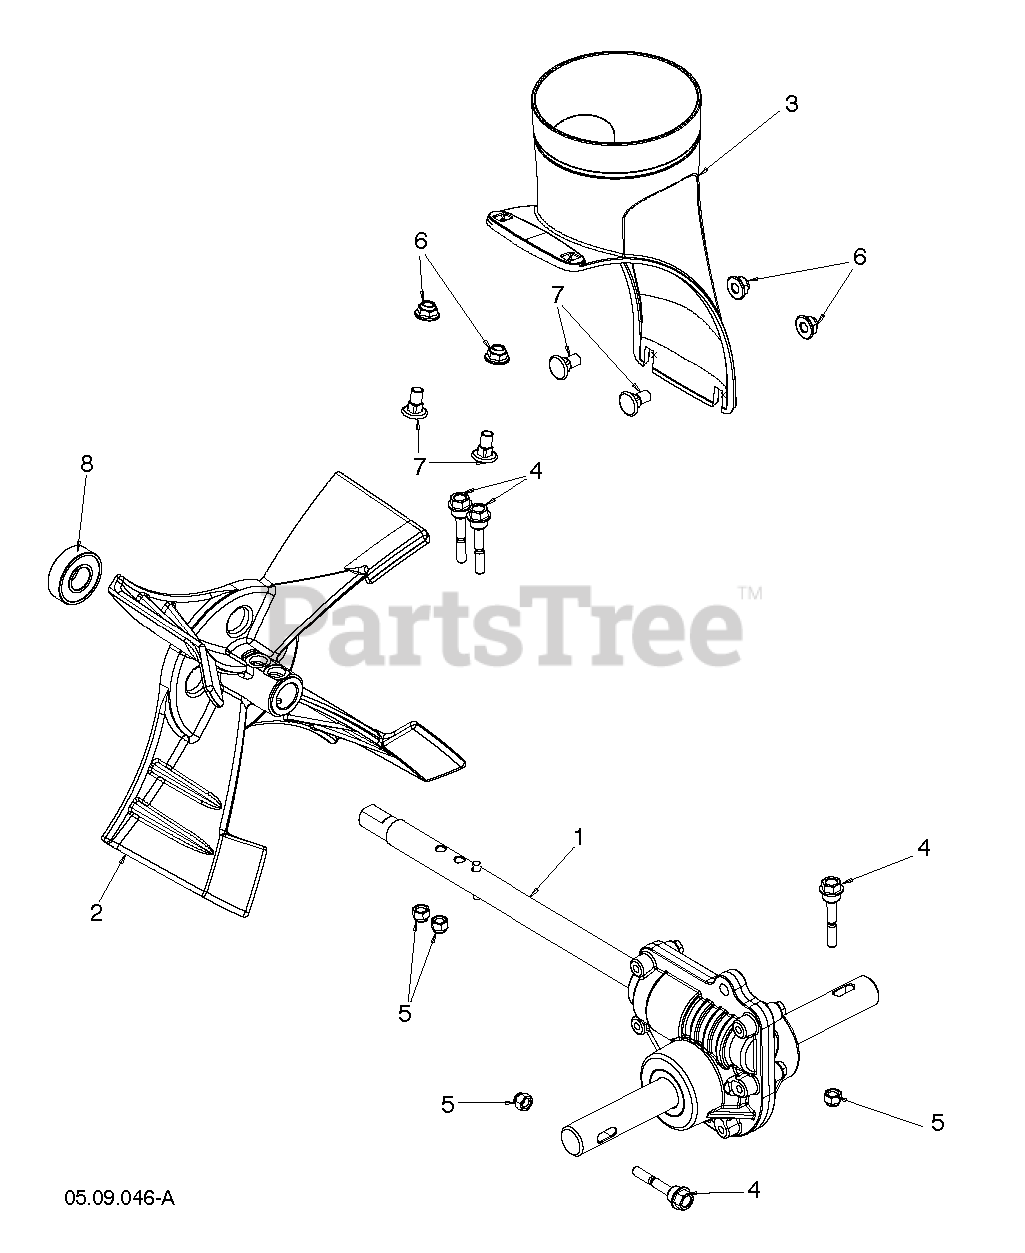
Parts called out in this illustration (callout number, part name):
1	GEARBOX CAST DD SHAFT
2	IMPELLER CAST.IRON.12IN MS 417
3	CHUTE BASE CAST ALUM HUSQ SIL
4	BOLT SHEAR HX HD 1/4-20 CLEAR
5	NUT HEXAGON 1/4-20 ST ZPB
6	NUT HEX FLG NYLOCK BLK 5_16-1
7	BOLT CARR WAFER BLK 5_16-18 X
